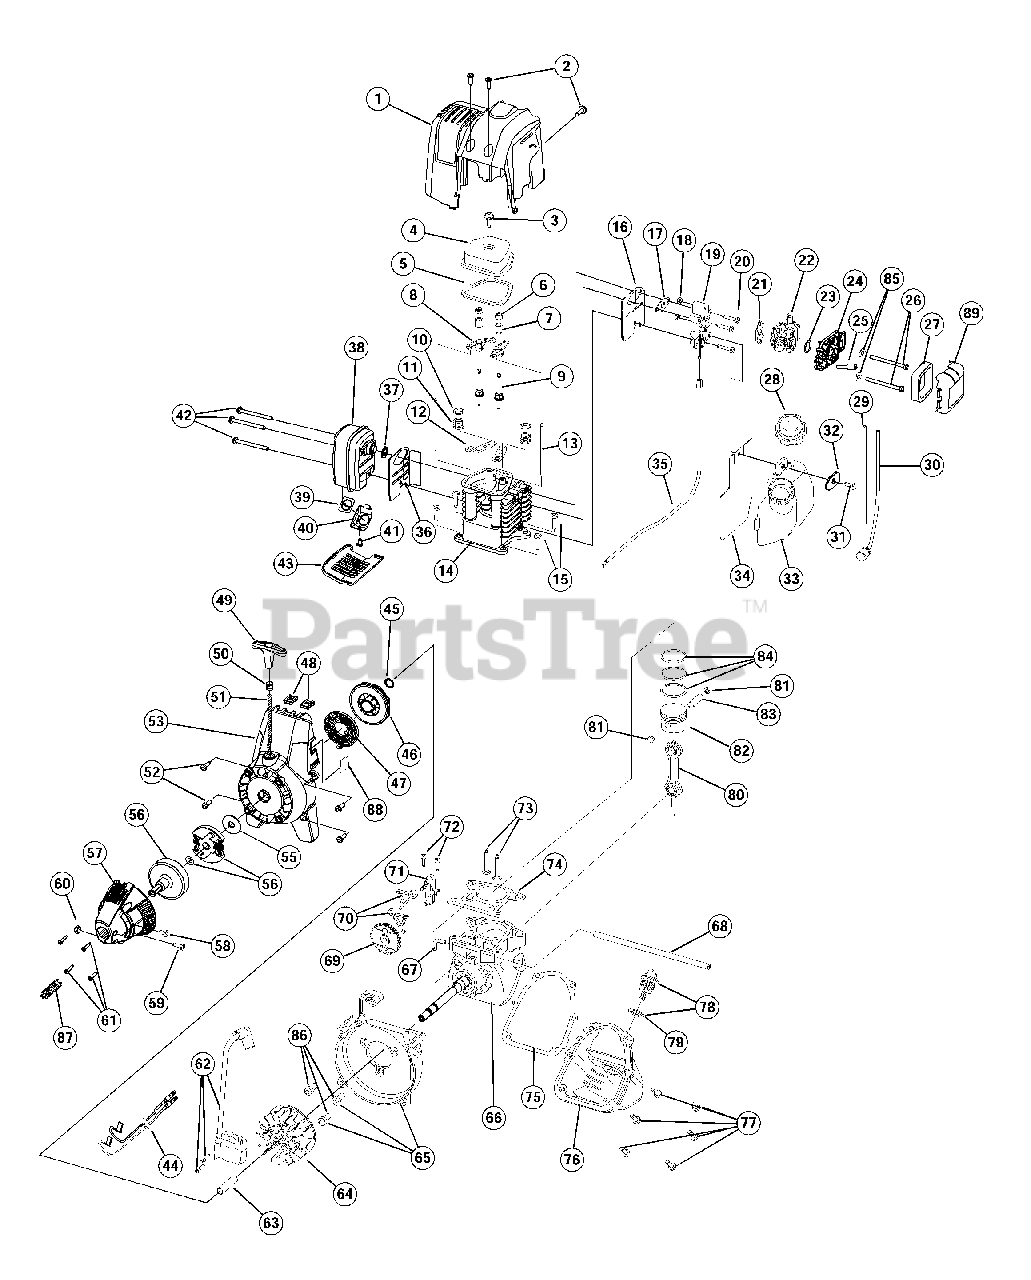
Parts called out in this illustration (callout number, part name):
1	Engine Cover
2	Engine Cover Screws
3	Valve Cover Screw
4	Valve Cover
5	Valve Cover Gasket
6	Rocker Adjustment Nut
7	Rocker Arm Pivot
9	Rocker Arm Stud
10	Valve Spring Retainer
11	Valve Spring
12	Push Rod Guide
13	Push Rod
14	Cylinder Assembly
15	Cylinder Screw
16	Intake Baffle
17	Carburetor Mount Gasket
18	Nut
19	Carburetor Mount
20	Carburetor Mount Screw
21	Carburetor Gasket
22	Carburetor with Primer
23	O-Ring, Carburetor
24	Air Filter/Choke Cover Assembly
25	Breather Tube
26	Air Filter Mounting Screw
29	Fuel Return Line
30	Fuel Pick-Up Line with Filter
33	Fuel Tank Assembly
34	Fuel Tank Shield
35	Throttle Cable
36	Muffler Baffle
37	Muffler Gasket
38	Muffler
39	Spark Arrestor Screen
40	Screen Cover
42	Muffler Mounting Screw
43	Muffler Cover
44	Switch Wire Assembly
45	Palnut
46	Recoil Pulley
47	Recoil Spring
49	Pull Handle
52	Starter Housing Screw
53	Starter Housing Assembly
54	Clutch Washer
55	Clutch with Spacer
56	Clutch Drum
57	Clutch Cover
58	Anti-Rotation Screw
59	Screw
61	Clutch Cover Screw
62	Ignition Module with Screws
64	Flywheel
65	Shroud Assembly with Screws
66	Crankcase Assembly
68	Breather Hose
70	Cam Follower Set
71	Cam Bracket
72	Cam Bracket Screw
73	Valves, Intake and Exhaust
74	Cylinder Gasket
75	Oil Pan Gasket
76	Oil Pan
77	Oil Pan Screw
78	Dipstick Assembly
80	Connecting Rod
81	Wrist Pin Button
82	Piston
84	Piston Ring Set
86	Shroud Screw
87	Compression Spring
89	Air Cleaner Cover
